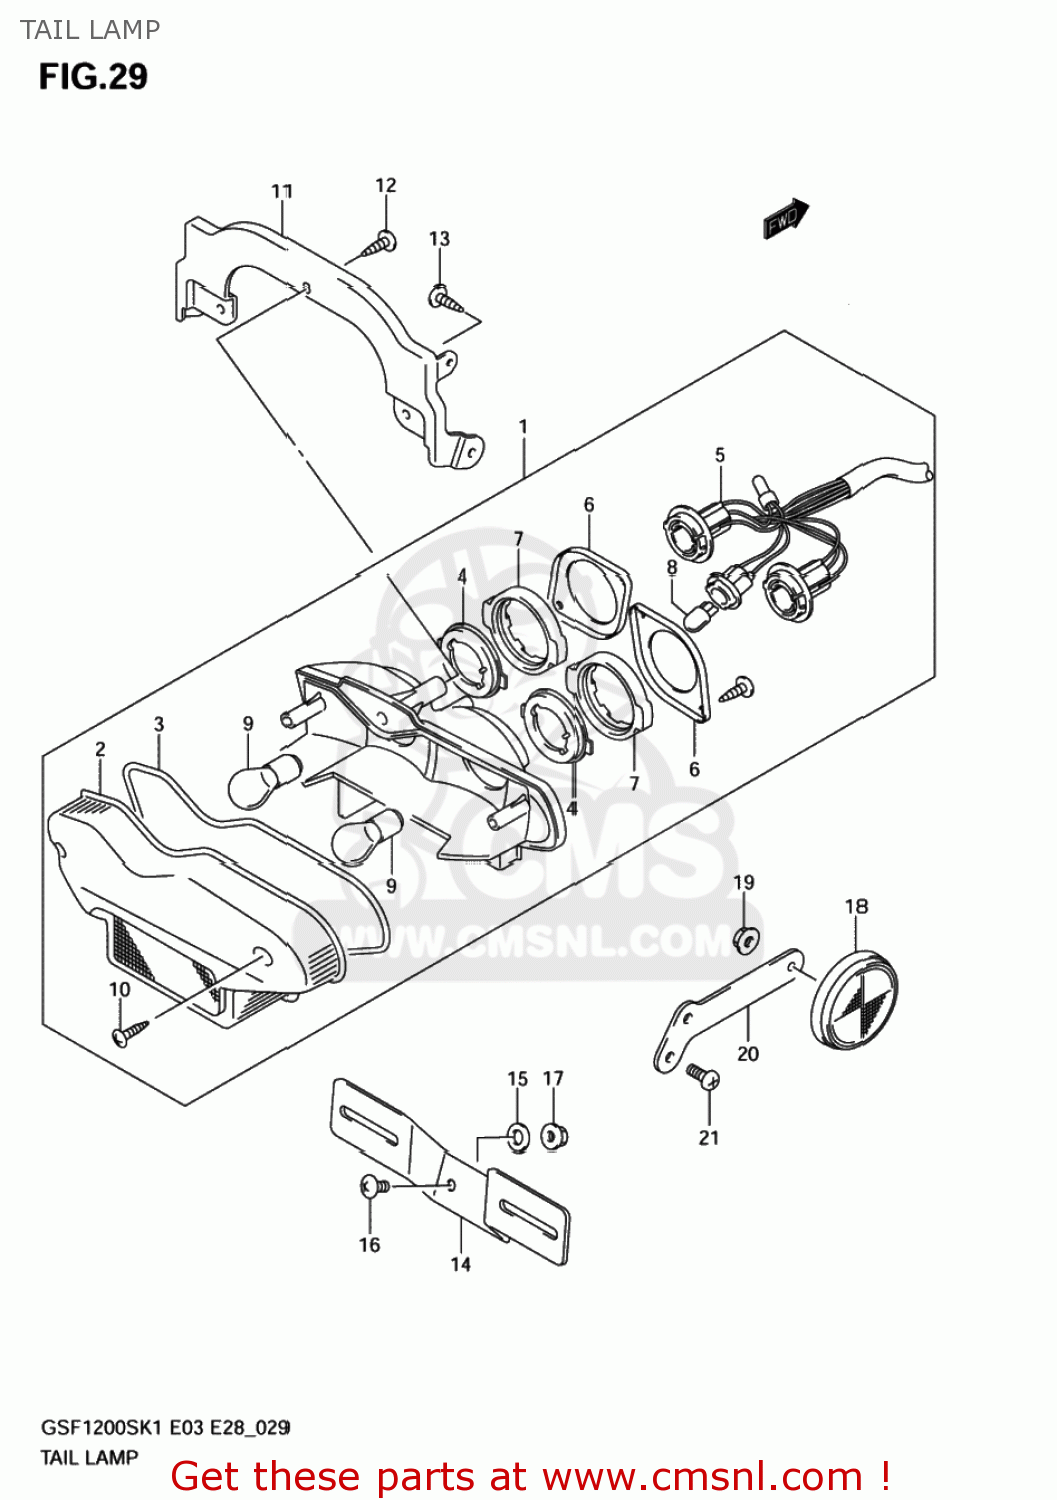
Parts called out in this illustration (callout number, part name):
1	LAMP ASSY,RR COMBINATION
2	LENS
3	GASKET (NAS)
4	PLATE NO.1
5	SOCKET & CORD
6	PLATE NO.2
7	CUSHION
8	BULB(12V5W)
9	BULB(12V21/5W)
10	SCREW
11	BRACKET,RR COMBINATION LAMP
12	SCREW
13	SCREW
14	BRACKET,LICENSE PLATE
15	WASHER(6.5X20X1.6)
16	SCREW
17	NUT
18	REFLECTOR ASSY,RR SIDE
19	NUT
20	BRACKET,RR SIDE RR,R
21	SCREW 6X12
